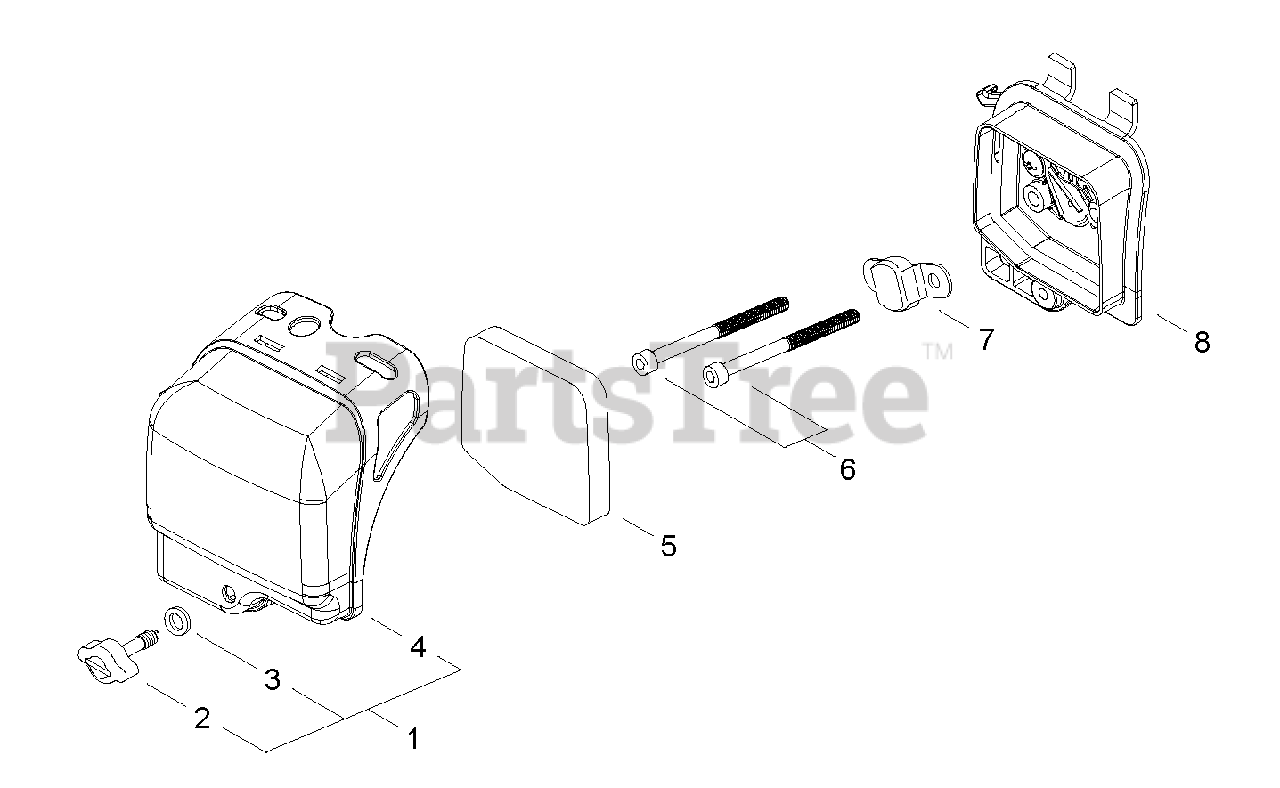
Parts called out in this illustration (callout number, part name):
1	AIR FILTER COVER ASSY
2	THUMBSCREW
3	WASHER - VYNYL
4	COVER, AIR FILTER
5	FILTER, AIR
6	SCREW - 5X60
7	PLATE, PREVENT
8	AIR FILTER CASE ASSY
